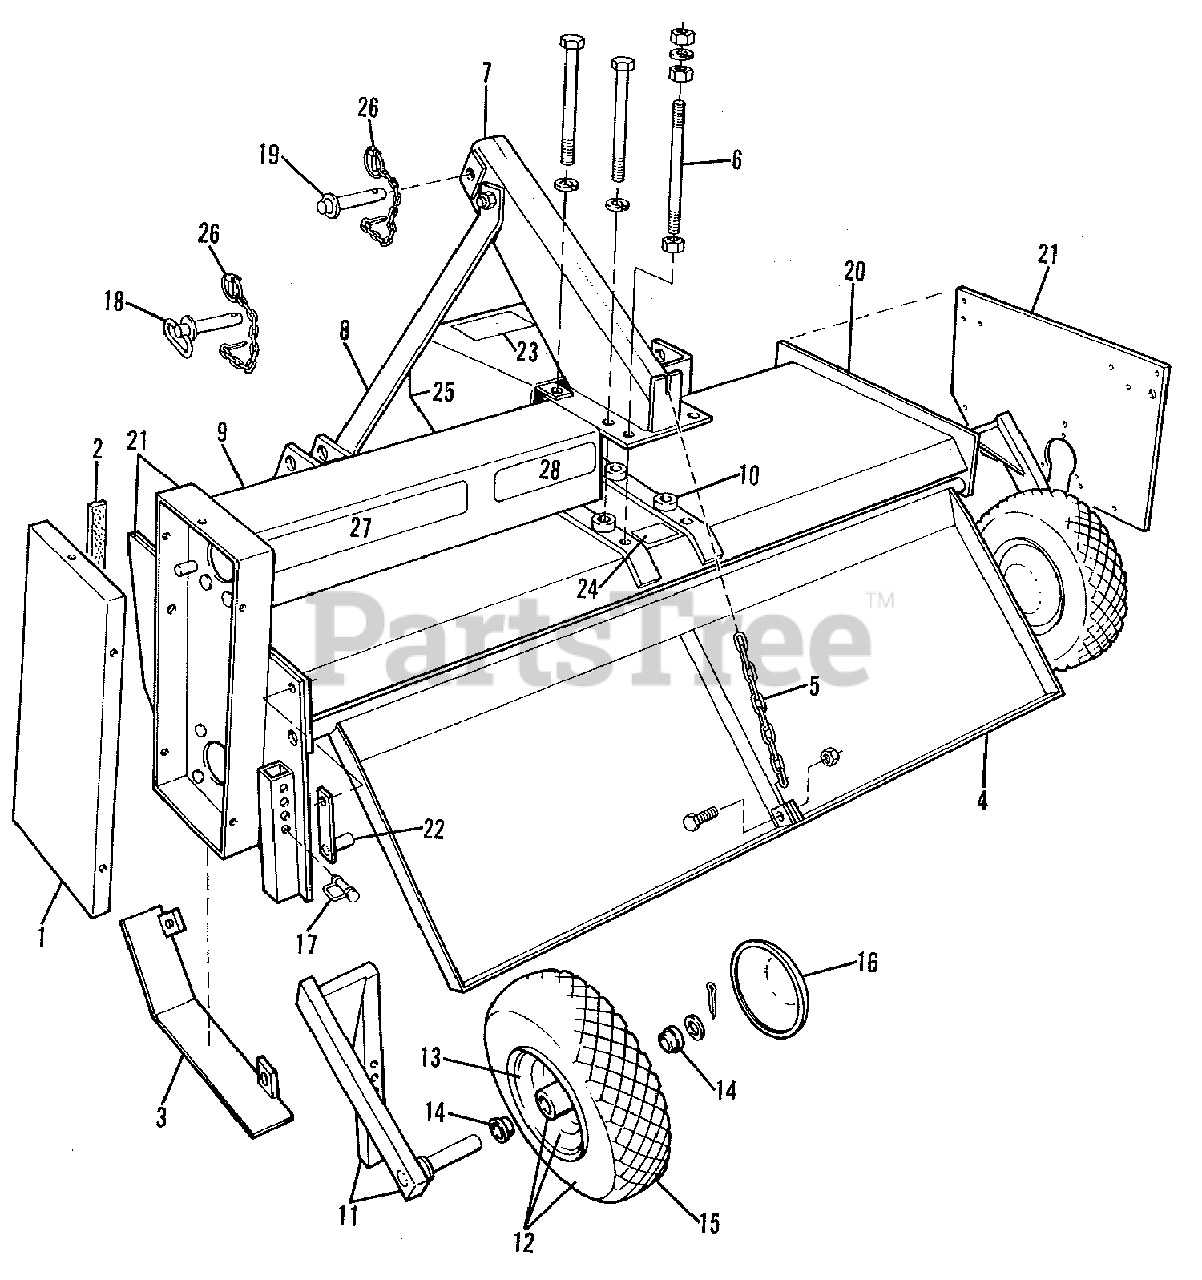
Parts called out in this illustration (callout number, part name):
1	COVER, Chain Case
1	SCREW, Self-Tap, 1/4 x 3/4
1	WASHER, Plain, 5/16 x 3/4 x 16 Ga.
1	LOCKWASHER, 1/4
2	STRIP, Cover Sealing
3	SKID ASSEMBLY, L.H.
3	SKID ASSEMBLY, R.H
3	CAPSCREW, 3/8NC x 1
3	NUT, Lock, 3/8NC
4	SHIELD ASSEMBLY, Trailing
5	CHAIN, Shield
5	CAPSCREW, 3/8NC x 1-1/4
5	NUT, Lock, 3/8NC
6	BOLT, Adjusting
7	MAST, Tower
7	CAPSCREW, 1/2NC x 1-1/4
7	LOCKWASHER, 1/2
8	SUPPORT, Tower Mast
8	CASCREW, 1/2NC x 3-1/2
8	LOCKWASHER, 1/2
9	COVER, Jackshaft
9	SCREW, Slotted, 5/16NC x 1
9	WASHER, Plain, 3/8 x 7/8 x 16 Ga.
9	LOCKWASHER, 3/8
10	SPACER, Gearbox
10	CAPSCREW, 1/2NC x 3-1/2
10	CAPSCREW, 1/2NC x 2
10	LOCKWASHER, 1/2
11	AXLE ASSEMBLY, L.H.
11	AXLE ASSEMBLY, R.H.
12	WHEEL ASSEMBLY, Complete
13	WHEEL ASSEMBLY
14	BUSHING, Hub
16	COVER, Wheel
17	PIN, Wheel Attaching
18	PIN, Side Moutning (7/8" Diameter)
19	PIN, Top Link (3/4" Diameter)
20	FRAME ASSEMBLY, Main Center
20	CAPSCREW, 3/8NC x 1
20	NUT, Lock, 3/8NC
21	PLATE, L.H. End
21	PLATE, R.H. End
22	PIN ASSEMBLY, Hinge
22	CAPSCREW, 3/8NC x 1-1/4
22	NUT, Lock, 3/8NC
23	DECAL, Warning (Tractor Linkage)
24	DECAL, Warning (Gearbox Oil Fill)
25	GUARD, Clutch
26	PIN ASSEMBLY, Retaining
27	DECAL (Allis-Chalmers)
28	DECAL (66 Model Identification)
